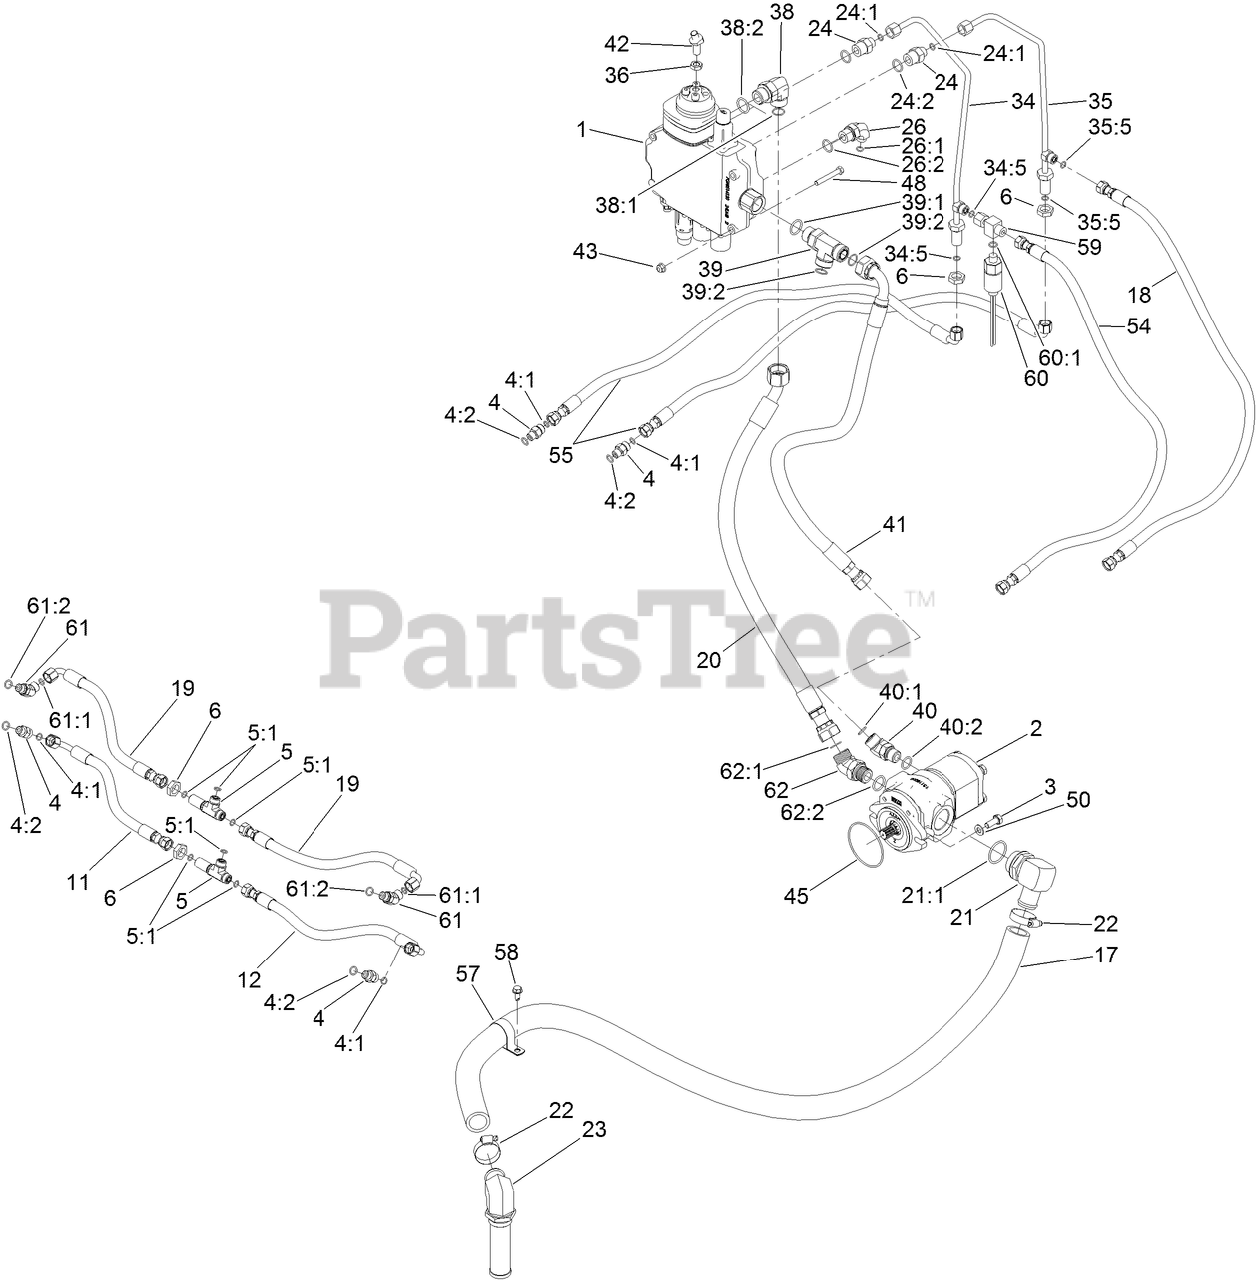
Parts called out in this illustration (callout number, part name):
1	LIFT VALVE ASM
2	GEAR PUMP ASM
3	SCREW-HH
4	FITTING-STRAIGHT
4:1	O-RING
4:2	O-RING
5	FITTING-TEE, BULKHEAD
5:1	O-RING
6	NUT-LOCK
11	HYD HOSE ASM
12	HYD HOSE ASM
18	HYD HOSE ASM
19	HYD HOSE ASM
20	HYD HOSE ASM
21	FITTING-HYD 90 SPCL
21:1	O-RING
23	STRAINER-SUCTION
24	FITTING-STR
24:1	O-RING
24:2	O-RING
26	FITTING-ELBOW 90
26:1	O-RING
26:2	O-RING
34	HYD TUBE ASM
34:5	O-RING
35	HYD TUBE ASM
35:5	O-RING
38	FITTING-ELBOW-90
38:1	O-RING
38:2	O-RING
39	FITTING-TEE
39:1	O-RING
39:2	O-RING
40	FITTING-HYD, 45 DEG
40:1	O-RING
40:2	O-RING
41	HYD HOSE ASM
42	SHAFT-CONTROL
43	NUT-HF, NI
45	O-RING
48	SCREW-HH
50	WASHER-FLAT
54	HYD HOSE ASM
55	HYD HOSE ASM
57	CLAMP-R
58	SCREW-HWH
59	FITTING-HYD, SPECIAL
60	SWITCH-PRESSURE
60:1	O-RING
61	FITTING-ELBOW, 45 DEG
61:1	O-RING
61:2	O-RING
62	FITTING-45 DEG
62:1	O-RING
62:2	O-RING
